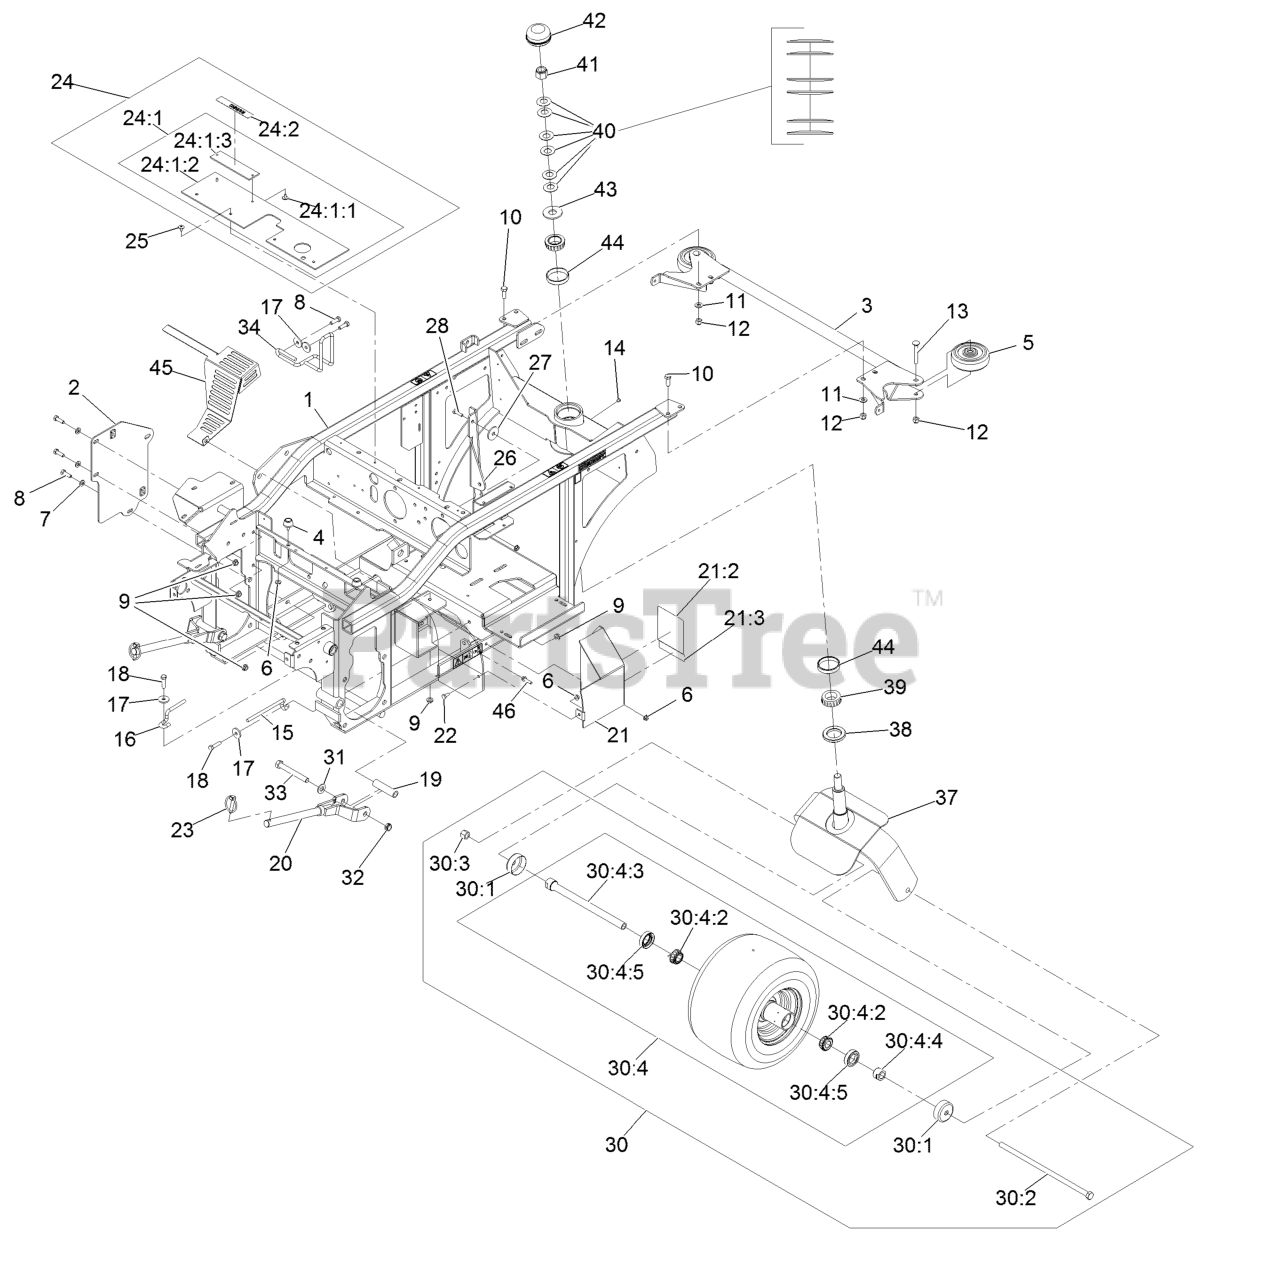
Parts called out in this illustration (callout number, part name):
1	Frame ASM
2	Plate-Support
3	Bumper-Rear
4	Bumper-Rubber
5	Roller-Bumper
6	Nut-Whizlock 1/4-20
7	Washer-5/16 SAE
8	Screw-HH 5/16-18 X 1
9	Nut-Whizlock 5/16-18
10	Screw-HH 3/8-16 X 1
11	Washer-3/8 SAE
12	Nut-Nyloc 3/8-16
13	Bolt-Carriage 3/8-16 X 2 1/2
15	Guide-Belt
16	Guide-Belt
18	Screw-HH 5/16-18 X 1 1/4
19	Spacer-Wheel, Short
21	Drive Shield ASM
21:2	Decal-Belt Routing
21:3	Decal-Warning
22	Screw-HH 1/4-20 X 5/8
23	Pin-Lynch
24	Lift Shield ASM
24:1	Shield-Lift
24:1:1	Rivet 3/16 X 1/4
24:1:2	Flap-Guard
24:1:3	Plate-Decal
24:2	Decal-Warning
25	Rivet 3/16 X 1/4
26	Brace-PTO
28	Screw-HH 1/4-20 X 1
30	Asm, Rear Caster Wheel W/Axle
30:1	Guard-Seal
30:2	Screw-HH 1/2-13 X 13
30:3	Nut-Nyloc 1/2-13
30:4	Asm, Wheel Tire And Brg 13X8.00-6 Sp
30:4:2	Bearing-Cone Tapered Roller
30:4:3	Axle Caster ASM
30:4:4	Spacer-Nut
30:4:5	Seal-Double Lip
31	Washer-1/2 SAE
32	Nut-Nyloc 1/2-13 Thin
33	Screw-HH 1/2-13 X 4
34	Guide-Belt
37	Fork-Rear Caster
38	Seal-Grease
39	Cone-Bearing Taper Roller
40	Washer-Spring Disc
41	Nut-Nyloc 3/4-10
42	Cap-Grease
43	Washer
44	Cup-Bearing Tapered Roller
45	Shield-Heat
46	Screw-HHF
